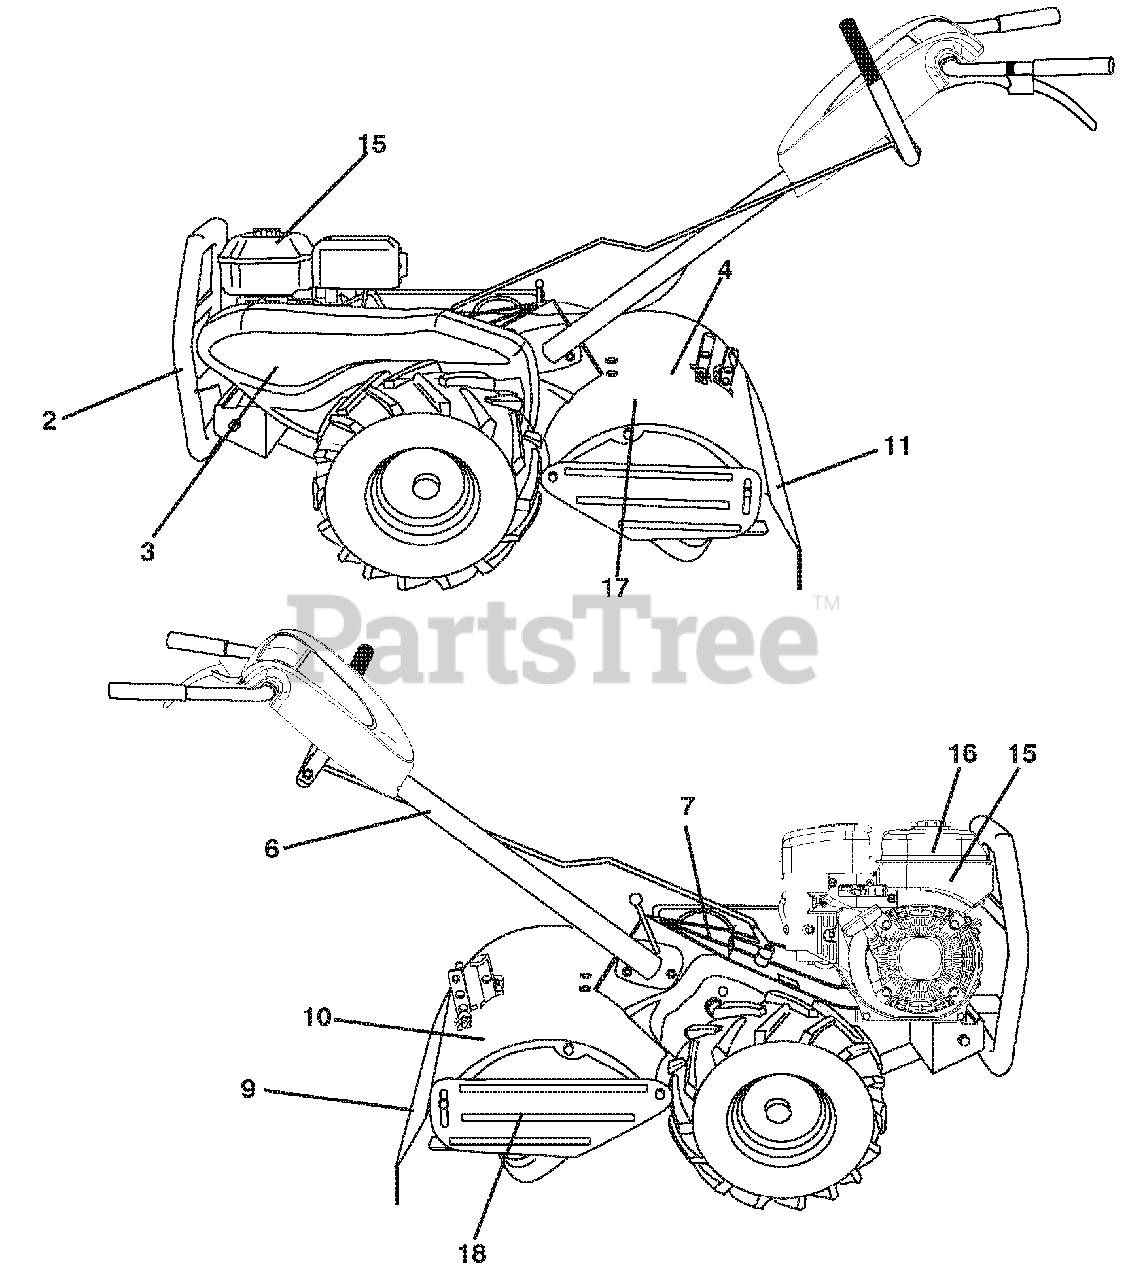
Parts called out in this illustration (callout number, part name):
2	DECAL, SUBARU TINE SHIELD
3	DECAL, BELT GUARD
4	DECAL, TINE SHIELD FORWARD
6	Decal, Hand Placement
7	Decal, Shift Indicator
9	Decal, Warning, DRT
10	DECAL, TINE SHIELD DRT REV
11	DECAL, TINE SHIELD GEAR
15	DECAL, ETHANOL
16	Decal, Spark Arrester
17	DECAL, TINE
18	DECAL, SIDE
